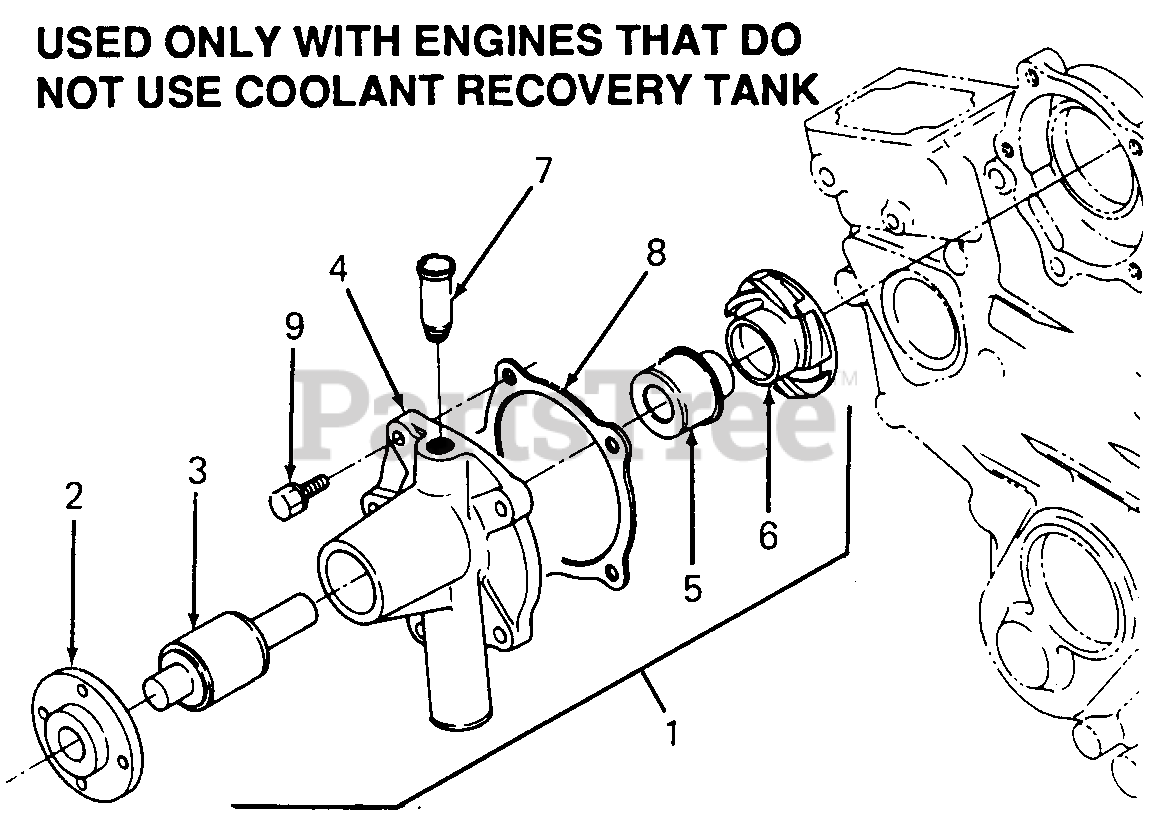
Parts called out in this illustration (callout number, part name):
1	Pump, Water
2	Flange, Water Pump
6	Impeller, Water Pump
7	Pipe, Water Return
8	Gasket, Water Pump
9	Screw, Hex Cap w/Washer
